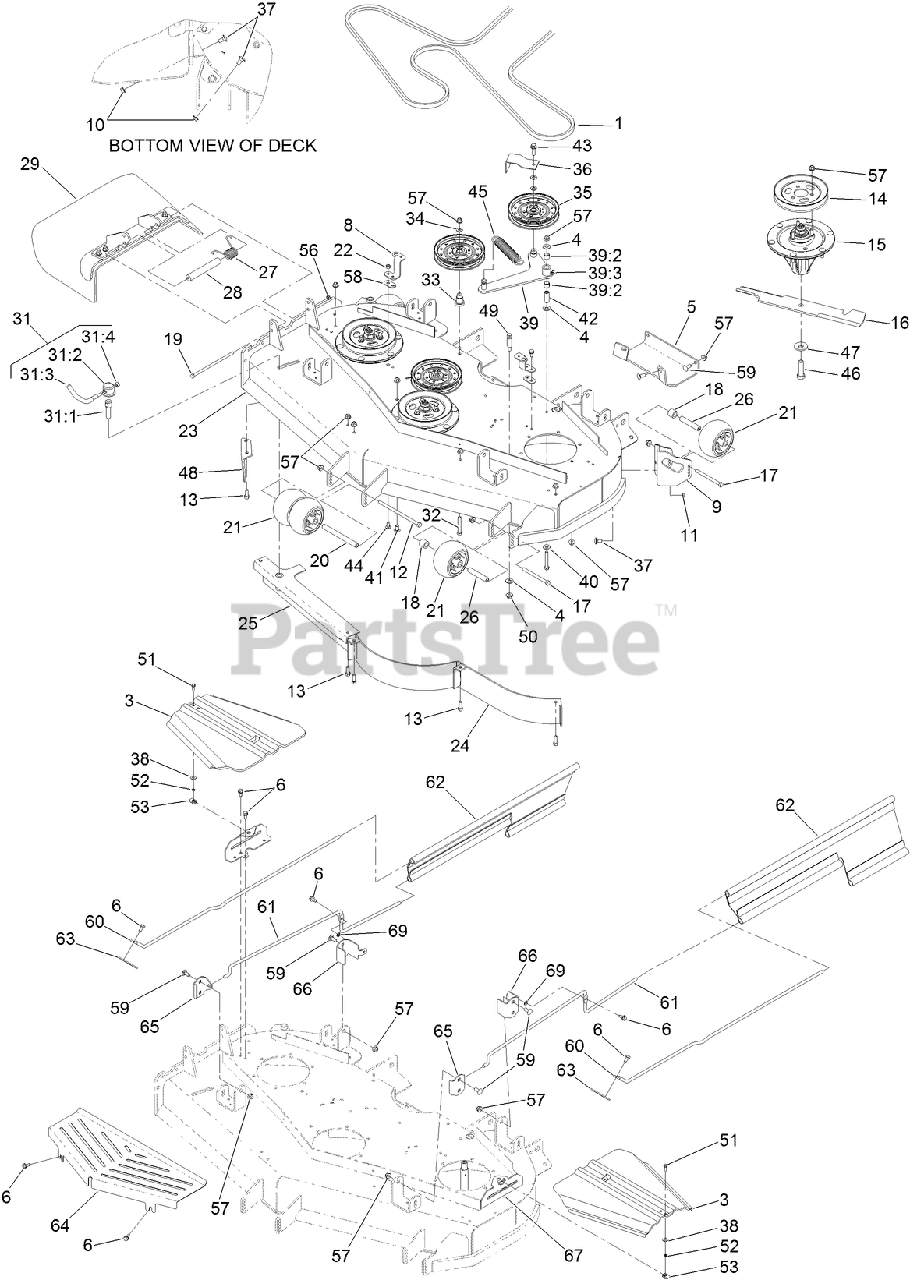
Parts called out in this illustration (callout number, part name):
1	BELT-V
3	COVER-BELT
4	WASHER-FLAT
5	PLATE-SKID
6	SCREW-HWHTF
8	BRACKET-COVER, TALL
9	MOUNT-WHEEL, LH
10	NUT-HHF, WHIZ
12	SCREW-HH
14	PULLEY-B SECTION
15	SPINDLE ASM
16	BLADE-18IN, HI FLOW
17	SCREW-HH
18	TUBE-SPACER
19	SCREW-HH
20	SPACER-WHEEL
21	ROLLER-SCALP, ANTI
22	NUT-LOCK, NI
23	DECK DECAL ASM
26	TUBE-SPANNER
27	SPRING-TORSION
28	SPACER
29	RUBBER DEFLECTOR ASM
31	LEVER ASM
31:1	SCREW-LOCK
31:2	CAP-LOCK
31:4	NUT-LOCK, NI
32	SCREW-HH
33	MOUNT-PULLEY
34	WASHER-FLAT
36	GUIDE-BELT
37	SCREW-HH
38	WASHER-THRUST
39	DECK IDLER ARM ASM
39:2	SLEEVE-BEARING
39:3	FITTING-GREASE, 90 DEG
40	WASHER-BELLEVILLE
41	SCREW-CARR
42	BUSHING
43	SCREW-HHF
44	SCREW-CARR
45	SPRING-EXTENSION
46	SCREW-BLADE
47	WASHER-BLADE BOLT, HEAVY
48	BAFFLE-DISCHARGE
49	PIN-THREADED, SPRING ANCHOR
50	NUT-HF
51	SCREW-HWH
52	NUT-RETAINER
56	NUT-LOCK, NI
57	NUT-HF, NI
58	SPACER-BELT COVER
59	SCREW-CARR
60	ROD-SUPPORT, UPPER
61	ROD-SUPPORT, LOWER
62	GUARD-SIDE
63	BRACKET-MOUNTING, UPPER ROD
64	SHIELD-FRONT
65	BRACKET-MOUNTING, FRONT
66	BRACKET-MOUNTING, REAR
67	BRACKET-SUPPORT, SPINDLE COVER
69	NUT-PUSH
